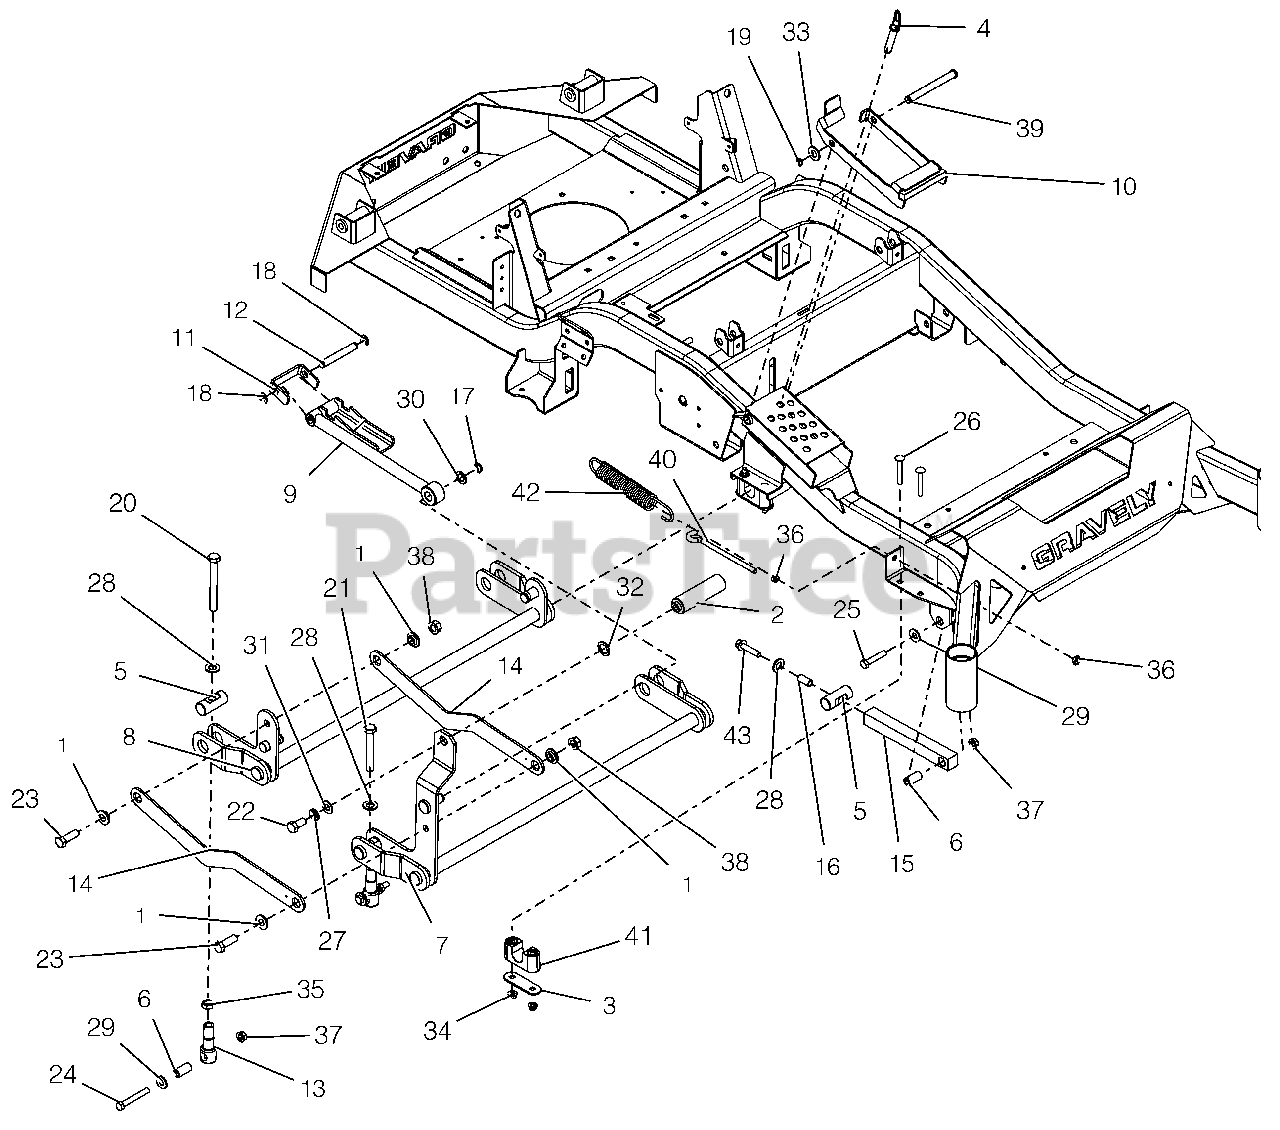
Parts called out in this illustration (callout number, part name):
1	BSHG-FLG .515X.750X.310X1.120
2	FOOT PEG, DECK LIFT
3	PLATE, BEARING SUPPORT
4	PIN, .50 X 2.00 USABLE LG BALL
5	PIN, DECK LIFT
6	SPACER, DECK LEVELING
7	WLDMT, FRONT DECK LIFT PIVOT
8	WLDMT, REAR DECK LIFT PIVOT
9	WLDMT, HOC ARM
10	BRKT, HOC TRANSFER LOCK
11	BRKT, HOC LINE
12	ROD, HOC PIVOT
13	LINK, DECK LIFT FORMED
14	LINK, DECK LIFT
15	LINK, DRAG
16	BSHG-SLV .385X.500X1.045
17	RG-RTNG-EXT .625X.050
18	RG-RTNG-EXT .500X.042 (E)
19	RG-RTNG-EXT .500X.050 (SNAP)
20	@BLT-HEX .5-13-4.5GR8 FULL THD
21	BLT-HEX .50-13X3.50 GR5 FTH
22	@BLT-HEX .50-13X1.00 GR5 YWZC
23	@BLT-HEX .50-13X1.50 GR5 YWZC
24	BLT-HEX .38-16X2.75 GR8 YWZC
25	@BLT-HEX .38-16X2.00 GR5 YWZC
26	BLT-RDHDSQSHNK .31-18X2.25 YWZ
27	@WSHR-LK .50X.125 REG YWZC
28	FLATWASHER 1/2 SAE HARD 15906
29	@WSHR-FL-STL.438X1.00X.083 YWZ
30	WSHR-FL-STL .630X1.005X.062 YZ
31	WSHR-FL-STL .505X1.00X.062YWZC
32	WSHR-FL-STL.754X1.125X.062YWZC
33	@WSHR-FL-STL.531X1.06X.095YWZC
34	@NUT-LK-CTR-FLG .31-18 YZ GR F
35	NUT-JAM .50-13 YWZC
36	NUT-HEX-JAM .375-16 YWZC
37	@NUT-LK-TOP-FLG .38-16 YWZC
38	@NUT-LK-TOP-FLG .50-13 YWZC
39	PIN-CLEV .50X4.75X4.55
40	BOLT,.38-16 X 5.25-.62 DIA EYE
41	ASM-BUSHING, DECK LIFT
42	SG-TENS .162X1.25X8.25 WLD 25
43	BLT,HEX-FLG .38-16X1.75 G5 ZCC
